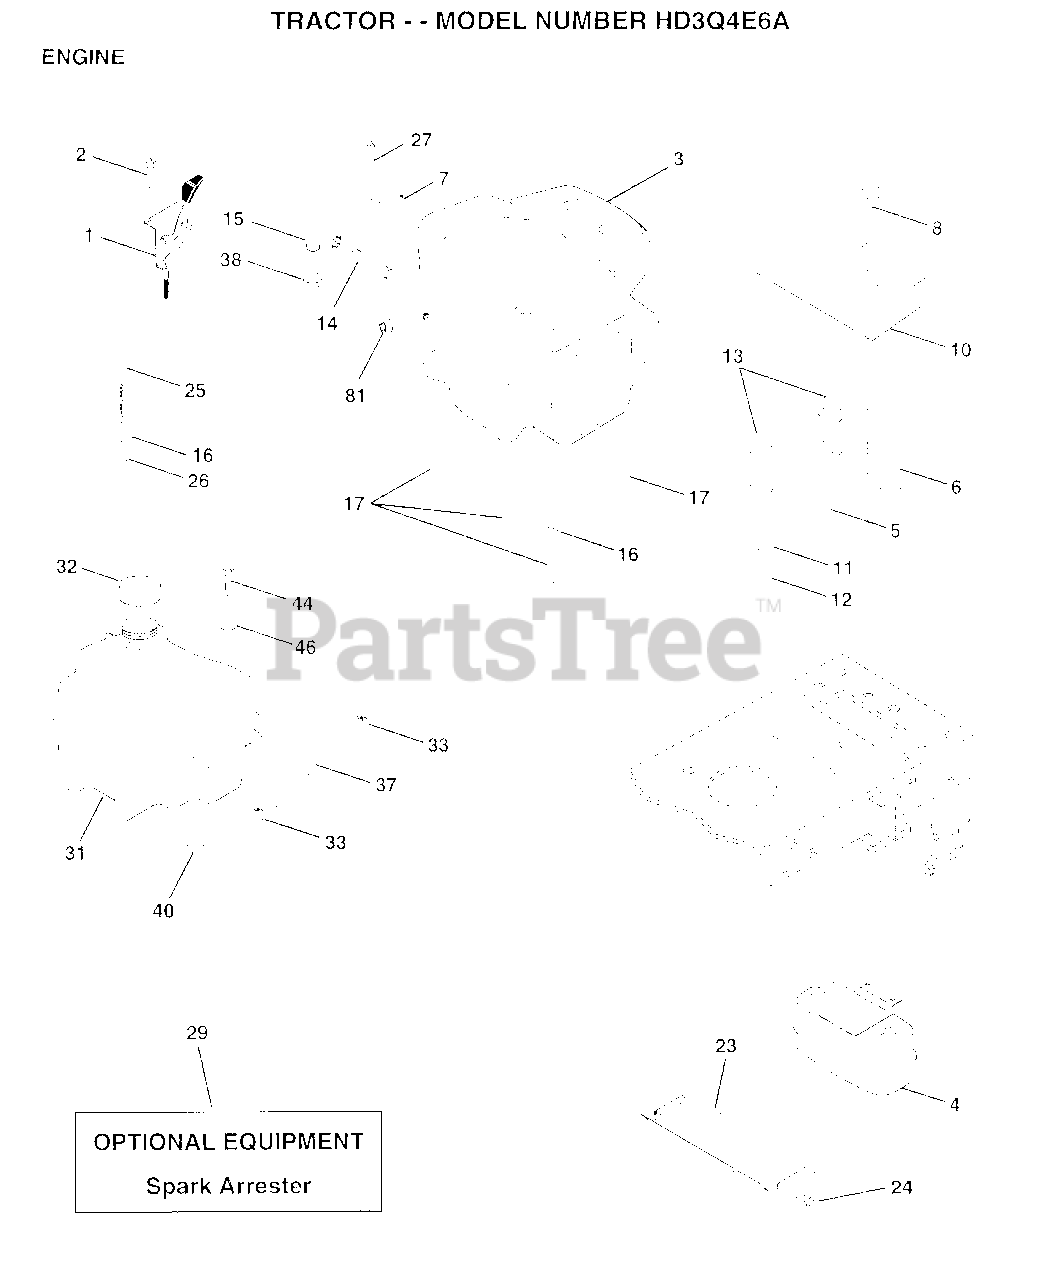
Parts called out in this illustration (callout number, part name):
1	CONTROL THRT 35.5
2	SCREW LT
4	MUFFLER.TW.LOTONE
5	EXHAUST.B&S.18.LH
6	EXHAUST.B&S.18.RH
7	CLAMP.TUBE.DBL.EN
8	BOLT.5/16-18.UNC
10	SHIELD.HEAT.
14	PIPE NIPPLE LT
15	ELBOW
16	LOCKWASHER
17	SCREW LT
23	HEAT SHIELD
24	SCREW
25	CONTROL.CHOKE.37
26	"NUT,KEPS 3/8-24IM"
27	SCREW.10-24X1/2
32	CAP ASM FUEL
33	HOSE CLAMP
37	LINE FUEL
44	SCREW HEX CRT
46	WASHER
81	NUT
